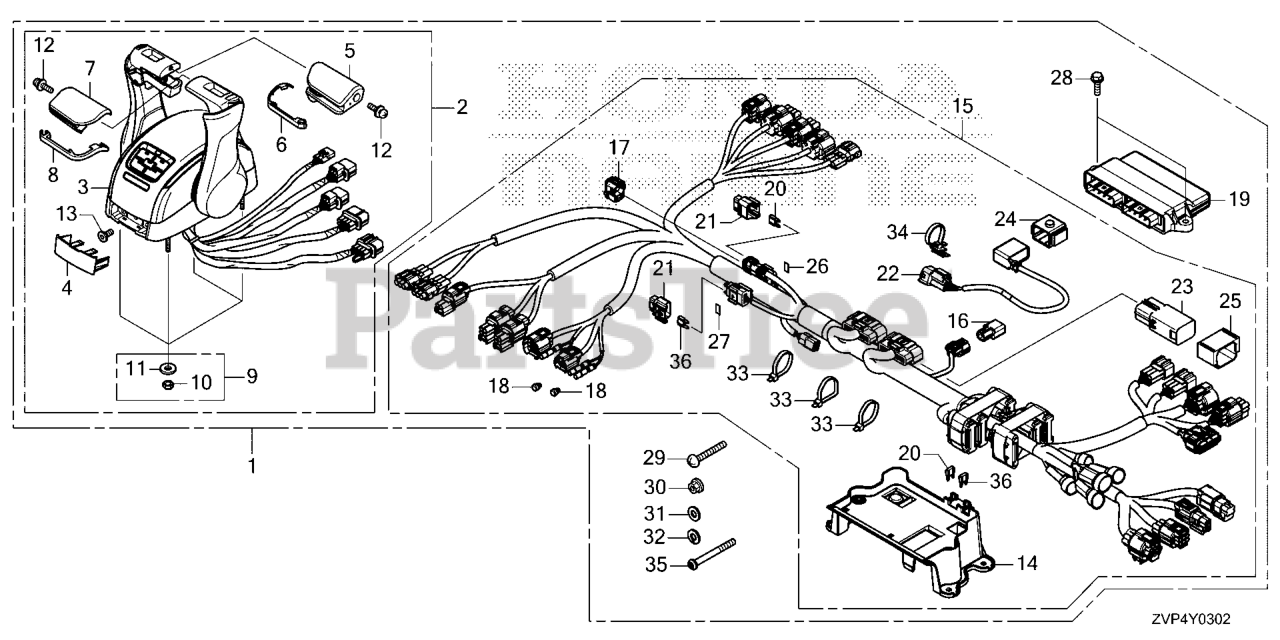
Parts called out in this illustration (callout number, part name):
1	BOX KIT, R/C
2	BOX ASSY., REMOTE CONTROL (TOP MOUNT DUAL)(RH)
3	CONTROL HEAD
4	COVER CAP
5	GRIP
6	GRIP PLATE
7	GRIP
8	GRIP PLATE
9	NUT SET, MOUNTING
10	NUT
11	WASHER
12	PAN HEAD SCREW
13	SOCKET HEAD CAP SCRE
14	CASE, CONTL UNIT
15	CASE ASSY,CONTL UNIT
15	CASE, CONTL UNIT
16	TERMINATOR ASSY.
17	CAP, DUMMY (WPC 4P 090 M) (RED)
18	PLUG, CONNECTOR (INNER) (TROLLING CONTROL)
19	UNIT ASSY., CONTL
20	FUSE, BLADE (3A)
21	COVER ASSY., FUSE
22	RELAY ASSY., CONTROL (NOT AVAILABLE)
23	RELAY ASSY., MAIN
24	HOLDER, RELAY (NOT AVAILABLE)
25	CUSHION, RELAY
26	LABEL, FUSE (3A)
27	LABEL, FUSE (5A)
28	BOLT, FLANGE (6X20)
29	SCREW, PAN (5X40) DUAL QTY = (8) (SINGLE)
30	NUT, FLANGE (5MM)
31	WASHER, PLAIN (5MM)
32	WASHER, SPG (5MM)
33	BAND, SELF-LOCK Use from Frame SN 3000253.
34	HOLDER, CONNECTOR (128.6MM) (NATURAL)
35	SCREW, PAN (5X65)
36	FUSE, MINI (5A)
